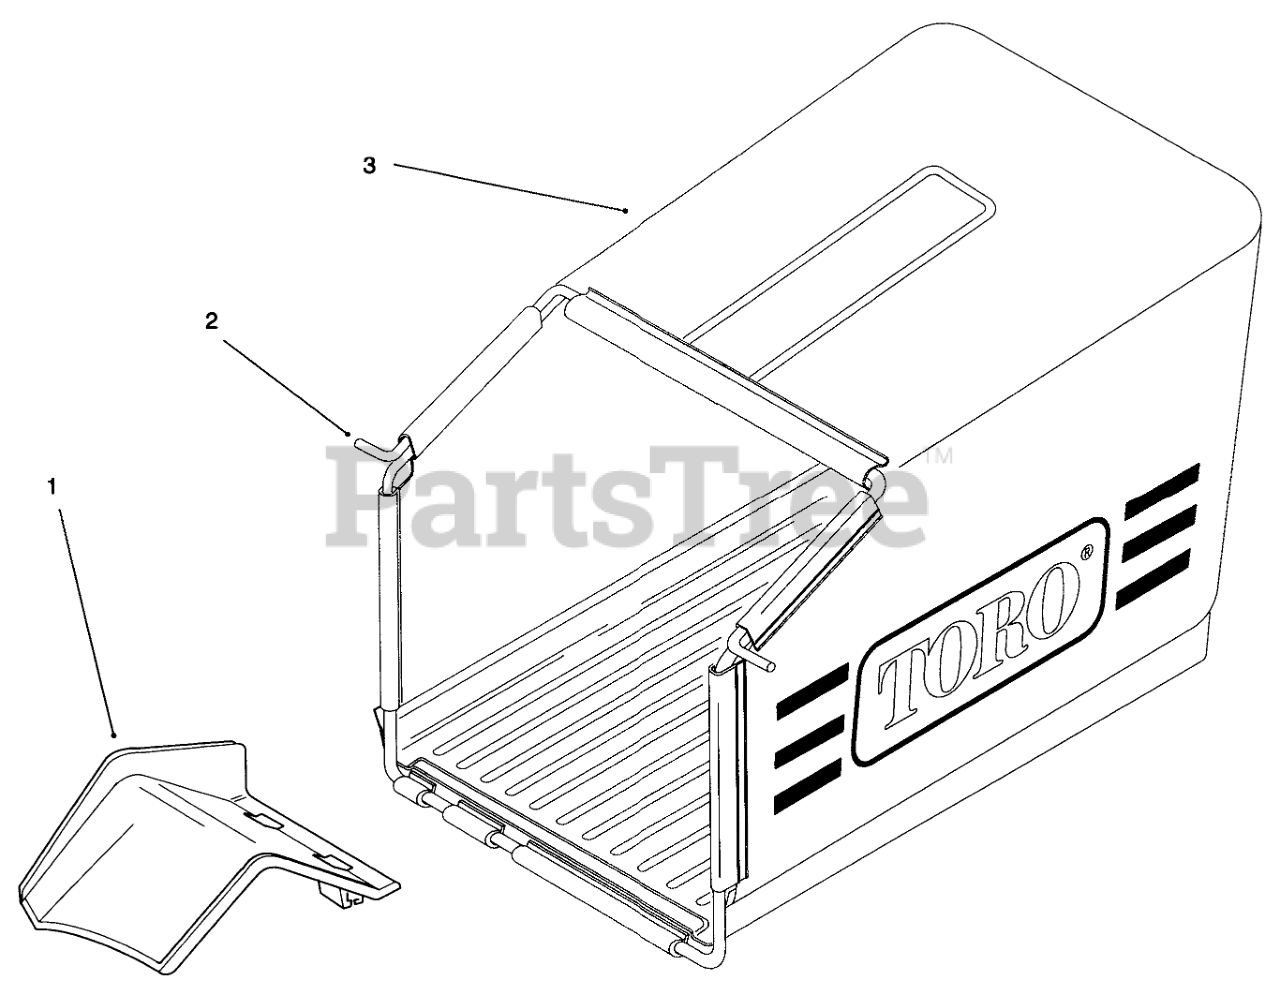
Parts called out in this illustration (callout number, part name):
1	REMOVER-BAG, GRASS
2	FRAME-BAG
3	BAG-GRASS
